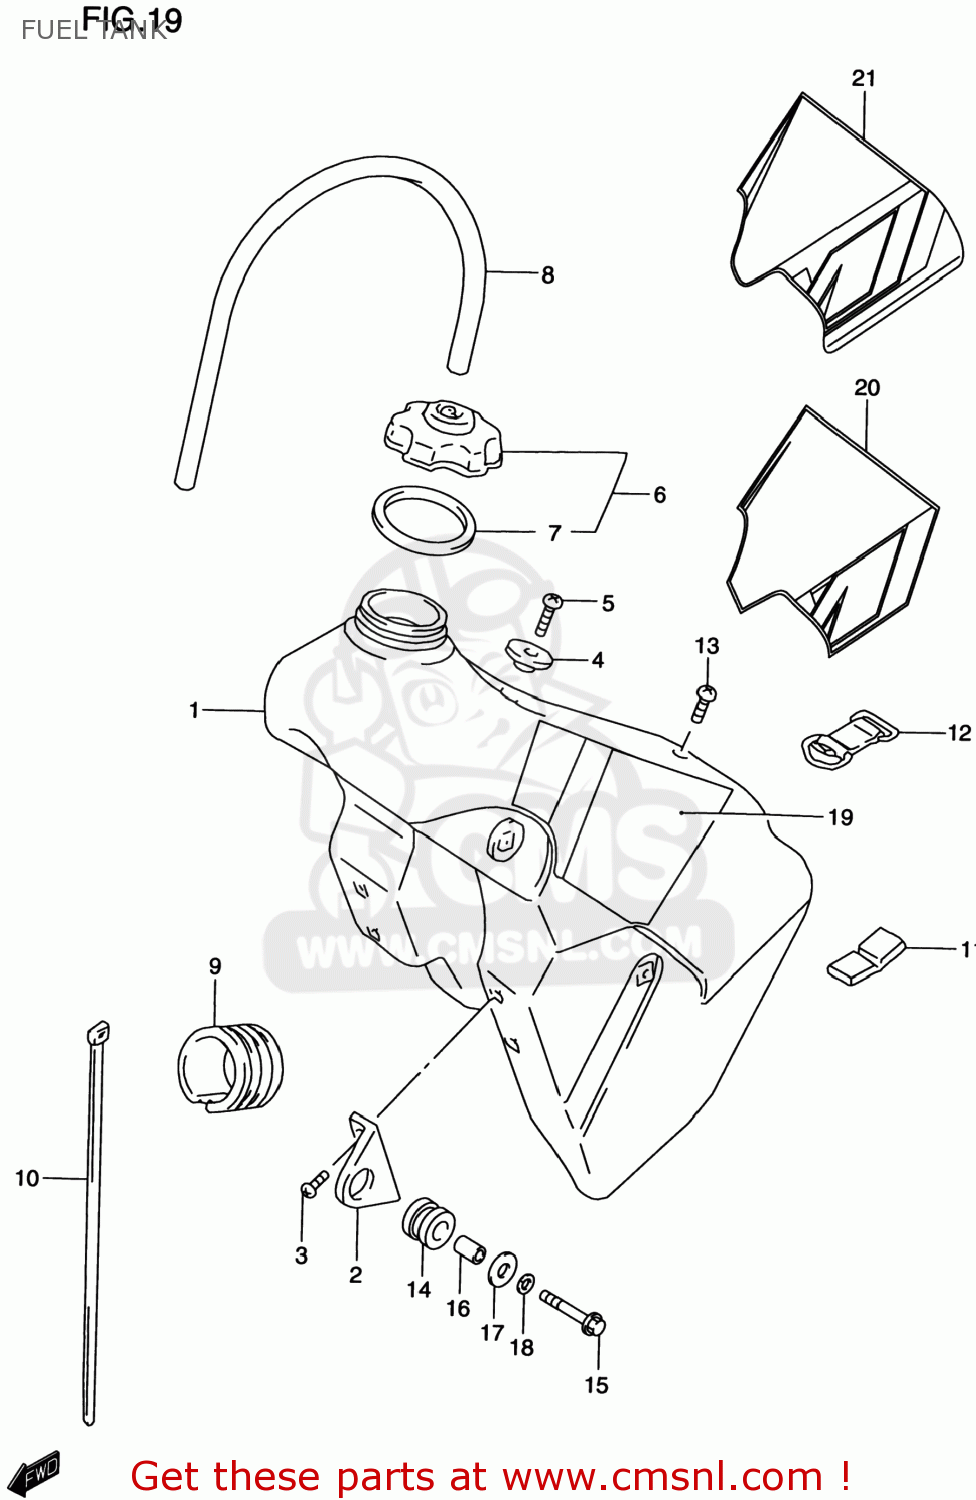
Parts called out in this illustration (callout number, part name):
1	TANK COMP,FUEL
2	BRACKET,FUEL TANK FR
3	SCREW
4	HOOK,SEAT FR
5	SCREW
6	CAP SET,FUEL TANK
7	GASKET,CAP (NAS)
8	HOSE (5.3X10.5X600)
9	CUSHION,FUEL TANK NO.1
10	CLAMP(L:300)
11	CUSHION
12	BAND,FUEL TANK RR
13	SCREW
14	CUSHION,MUFFLER
15	BOLT,G/S SWITC
16	SPACER(6.5X9X13.5)
17	WASHER(6.5X24X1.2)
18	LOCK WASHER
19	TAPE SET,FUEL TANK
20	TAPE SET,FUEL TANK
21	TAPE SET,FUEL TANK
